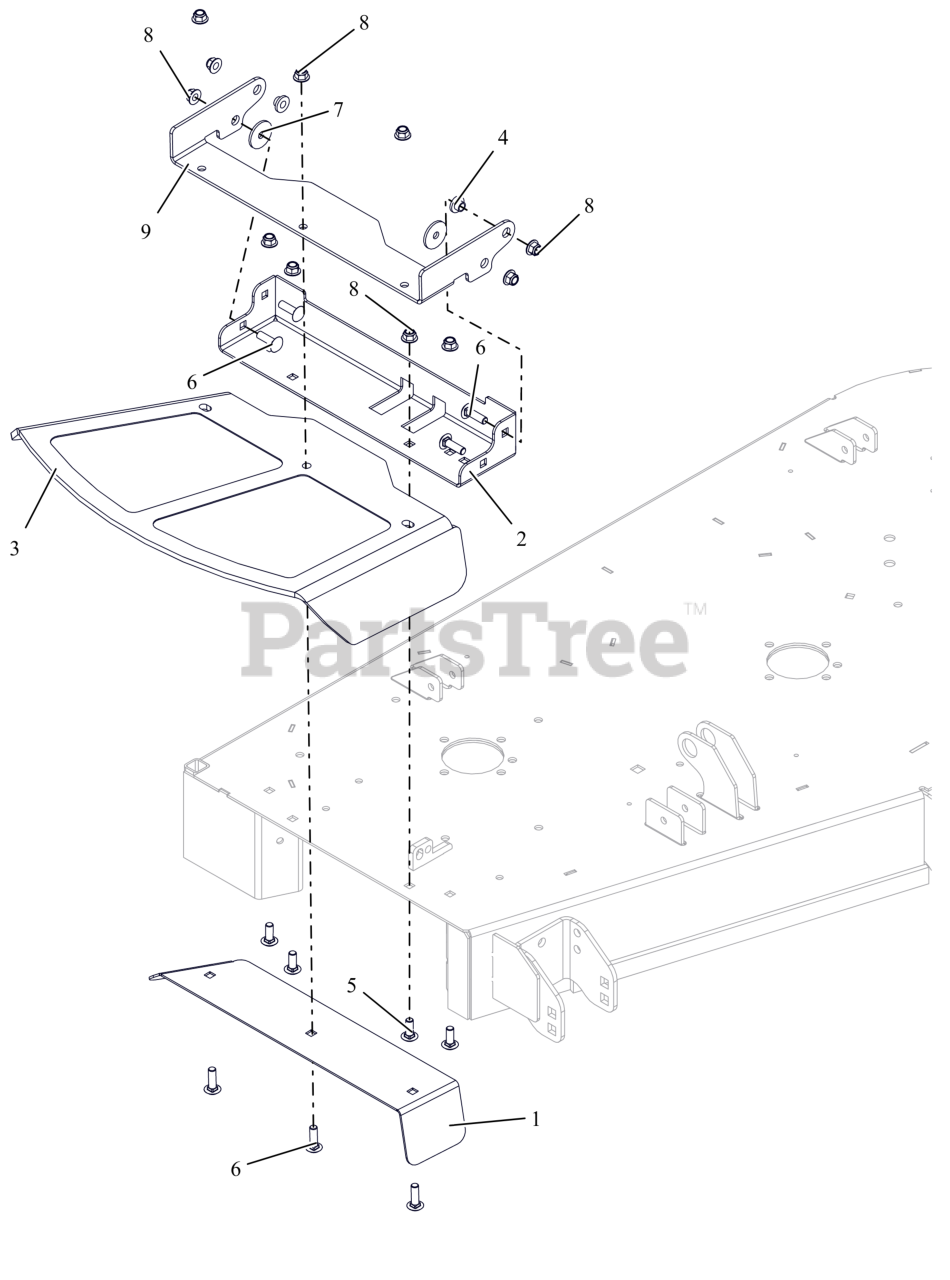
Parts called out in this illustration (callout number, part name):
1	PLT, DISCH. CHUTE CLMP-CE
2	WMT, DISCH. CHUTE-CE-W/SAFETY
3	CHUTE, FORMED RUBBER DISCHARGE
4	BSHG-FLG .385X.500X.875X.406
5	BLT,RHSSN .38-16X1.00 G5 ZCC
6	BLT,RHSSN .38-16X1.25 G5 ZCC
7	WSHR, FLT .380X1.50X.125 ZCC
8	NUT,NYL-FLG .38-16 GF ZCC
9	BRKT, CE CHUTE MTG (ORANGE)
